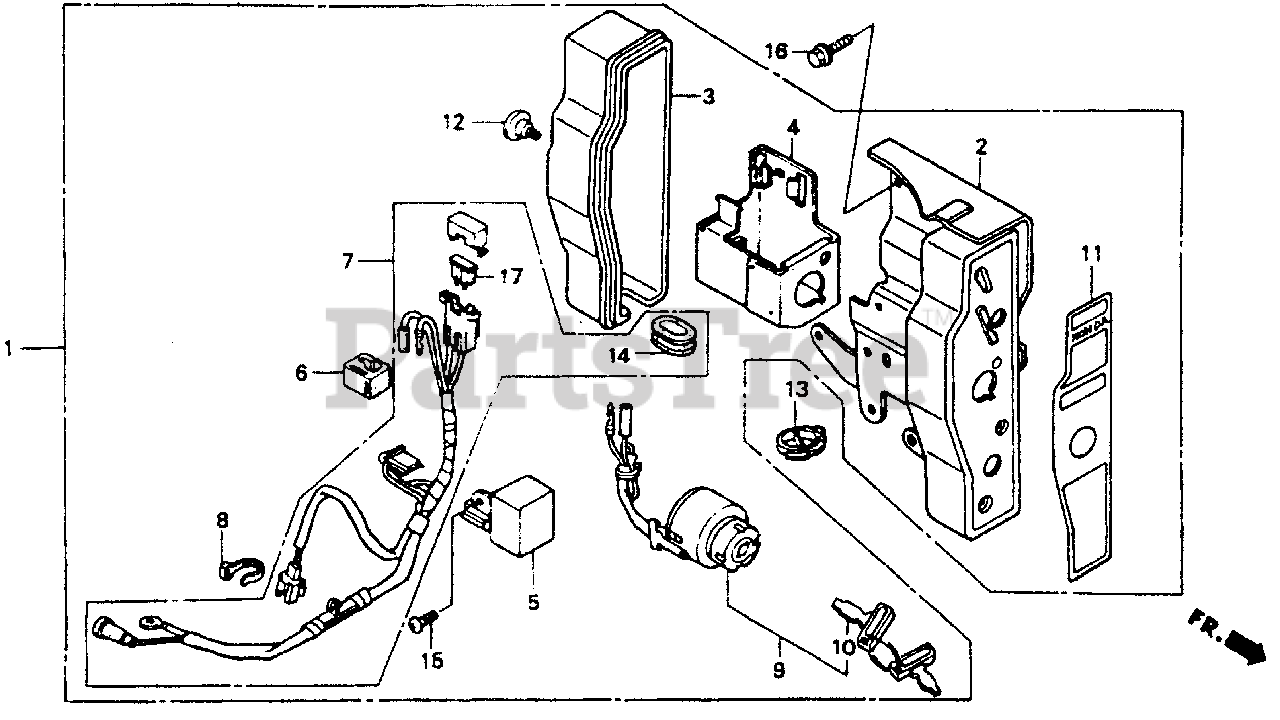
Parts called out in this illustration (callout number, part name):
1	BOX ASSY., CONTROL *NH116M* (EXTERNAL) (URBAN SILVER METALLIC)
2	PANEL, CONTROL *NH116M* (URBAN SILVER METALLIC)
3	CASE, CONTROL
4	BRACKET, CASE MOUNTING
5	RECTIFIER, SILICON
6	SUSPENSION, CONNECTOR
7	WIRE HARNESS ASSY., CONTROL
8	BAND
9	SWITCH ASSY., COMBINATION
10	KEY
11	MARK, CONTROL BOX (EXTERNAL)
12	SCREW, SPECIAL (6X12)
13	CLIP, WIRE HARNESS
14	GROMMET, WIRE HARNESS
15	SCREW, PAN (6X12)
16	BOLT, FLANGE (6X16)
17	FUSE, BLADE (15A)
